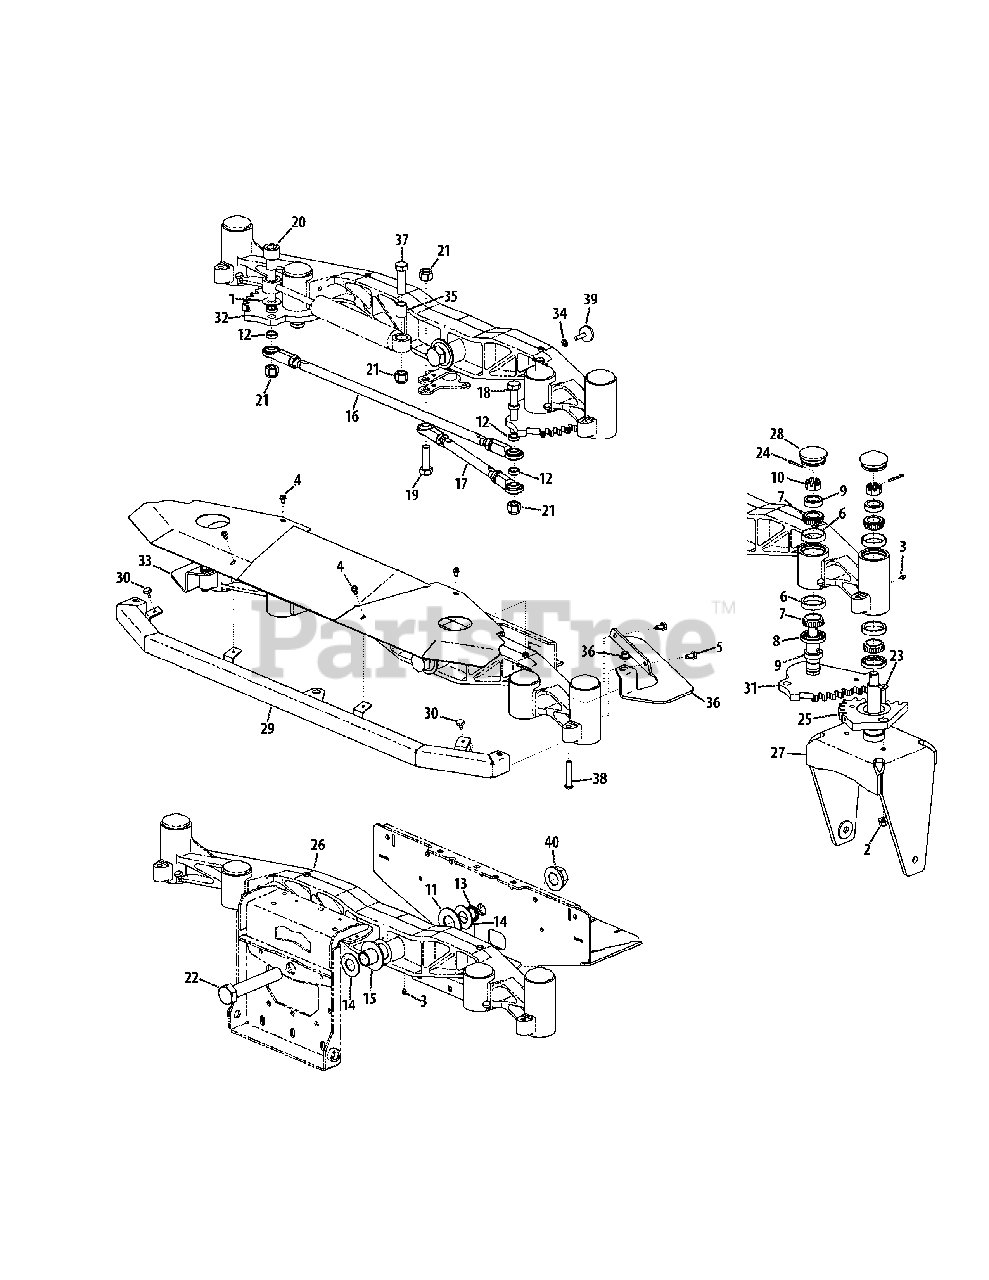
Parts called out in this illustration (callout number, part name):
1	Washer, .655 x 1.5 x .055
2	Flange Counter Lock Nut, 3/8-16
3	Grease Fitting, 1/4-28
4	Hex Flange Screw, 1/4-20 x .500
5	Flange Screw, 5/16-18 x .625
6	Bearing Cup
7	Cone Bearing
8	Seal
9	Seal Ring
10	Slot Nut, 3/4-16
11	Bell Washer, 1.25 x 2.50 x .180
12	Spacer, .635 x .880 x .312
13	Self-Lock External Retainer
14	Washer, 1.00 x 2.00 x .075
15	Spacer, 1.00 x 1.25 x 3.47
16	Tie Rod Assembly, 1/2-20 x 28
17	Tie Rod Assembly, 5/8-18 x 14
18	Hex Screw, 5/8-11 x 4.00
19	Hex Screw, 5/8-11 x 1.75
20	Shoulder Bolt, .872 x 1.030 x 2.88
21	Hex Lock Nut, 5/8-11
22	Hex Screw, 1-14 x 5.5
23	Hex Screw, 3/8-16 x 1.50
24	Cotter Pin, 5/32 x 1.25
25	Yoke Steering Gear
28	Axle Grease Cap
29	Axle Bumper Assembly
30	Rubber Bumper, .62 x .22
31	LH Steering Gear Assembly
32	RH Steering Gear Assembly
35	Spacer, .635 x .875 x 1.031
38	Screw, 3/8-16 x 2.25
39	Adjustable Skid Shoe
40	Flange Top Lock Nut, 1.0-14
